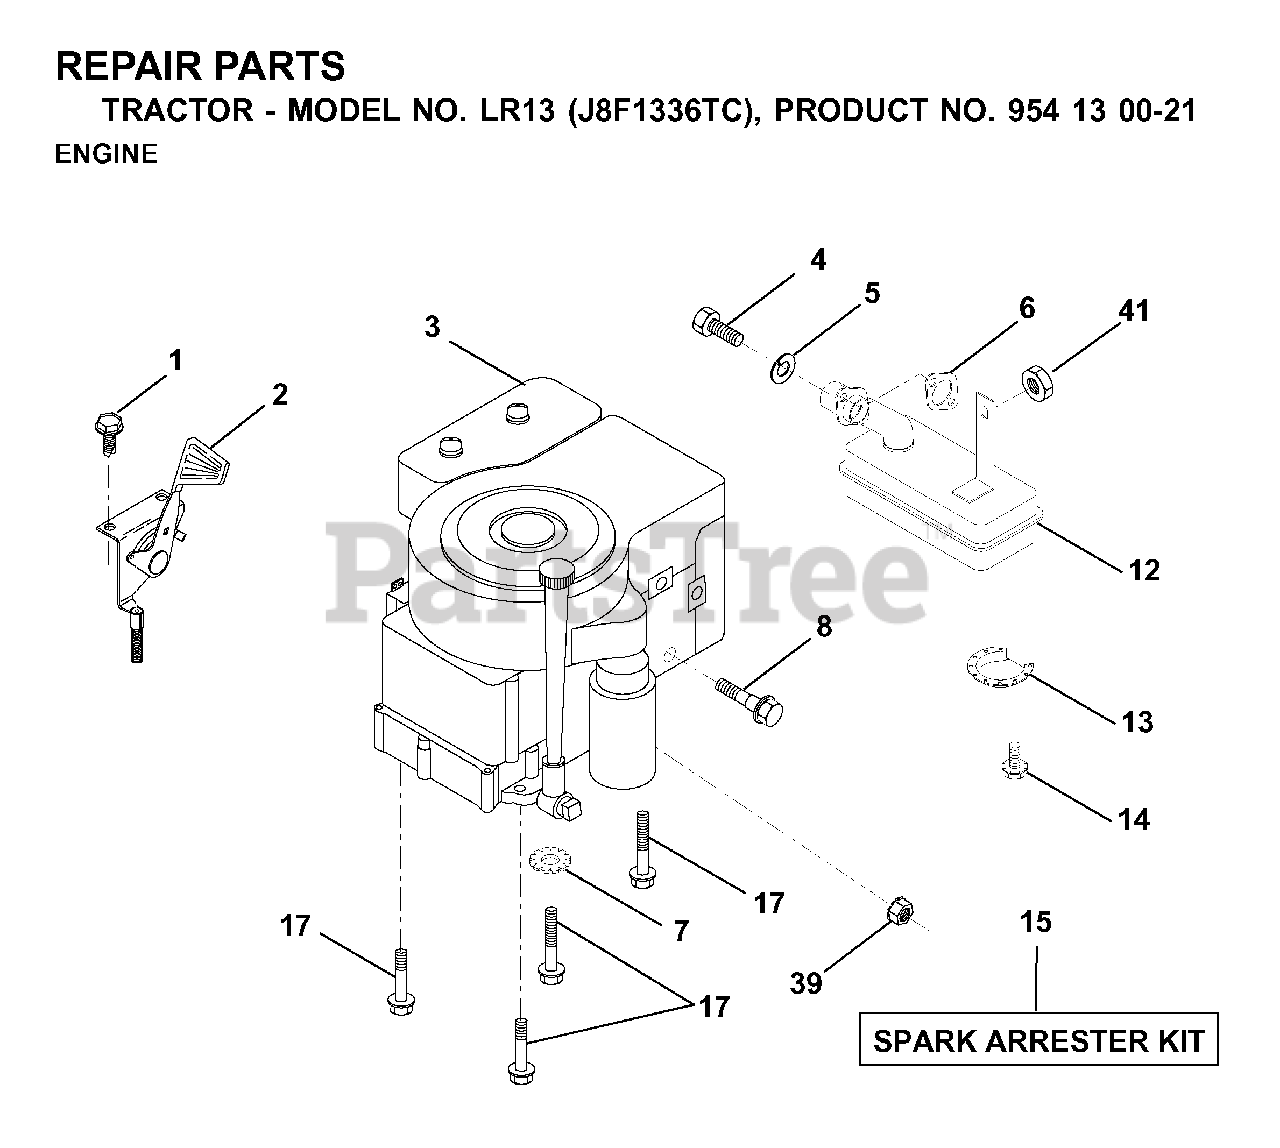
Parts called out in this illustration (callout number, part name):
1	SCREW LT
2	CONTROL THROTTLE
5	LOCKWASHER
6	REPL BY 532 27 22-93
7	LOCKWASHER
8	SHOULDER BOLT ST
13	DEFL MUFFLER LTV
14	SCREW
15	ARRESTER SPARK (OPTIONAL)
17	SCREW LT
39	NUT FLANGE 1/4-20 STARTER NUT
41	NUT LOCK HEX FLANGE 5/16-18
